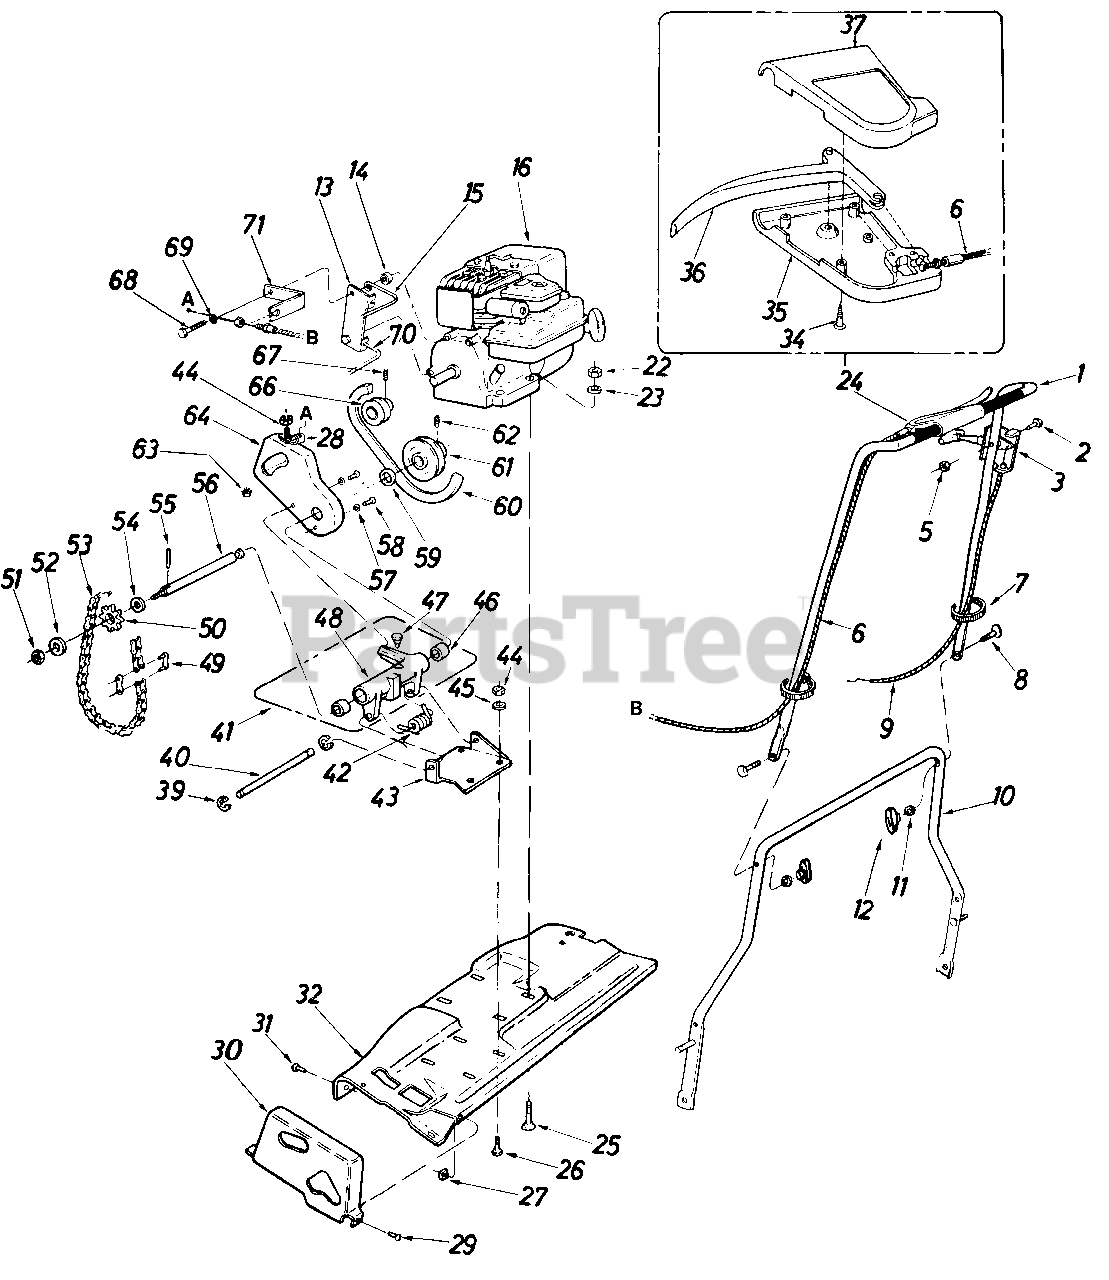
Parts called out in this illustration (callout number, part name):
1	Upper Handle Ass'y.
2	Rd. Hd. Scr. 1/4-20 x 1.88" Lg.
3	Throttle Control Ass'y.
5	Capped Wash. Z-Nut
6	Clutch Control Cable
7	Cable Tie
8	Speclal Scr. 5/16-18 x 1.75" Lg.
9	Throttle Cable
10	Lower Handle Ass'y.
11	L-Wash. 5/16
12	Handle Knob
13	Belt Keeper Brkt.
14	Spacer
15	Belt Keeper-Upper
16	Engine
22	Hex Nut 5/6-18 Thd.
23	L-Wash. 5/16
24	Clutch Control Ass'y.
25	Carriage Bolt 5/16-18 x 1.375" Lg.
26	Scr. 1/4-20 x .625" Lg.
27	Hex L-Nut 10-32 Thd.
28	Clevis Lanyard Fitting
29	Ph. Hd. Scr. 10-32 x .375" Lg.
30	Chain Guard
31	Hex Sems Scr. 5/16-24 x .50 Lg.
34	Slotted Oval Self-Tap Scr. #10 x .87" Lg.
35	Rear Control Cover
36	Lever Clutch Control
37	Front Cover Control
39	Retaining Ring
41	Jack Shaft Hsg. and Brg. Ass'y.
42	Spring
43	Bracket
44	Hex Nut 1/4 -20 Thd.
45	1/4 Split L-Wash.
46	Bearing
47	Oiler
48	Jack Shaft Hsg.
49	Connector Link
50	Sprocket
51	Hex Jam Nut 5/16-24
52	Washer
53	Chain
54	Wash. 5/8 x 15/16
56	Jack Shaft
57	Washer
58	Ph. Hd. Scr. 10-32 x .50" Lg.
59	Wash. 5/8 x 15/16
60	"V" Belt
61	Pulley Ass'y.
62	Roll Pin
63	Hex Nut 1/4-20 Thd.
64	Belt Guard Ass'y.
66	Pulley
67	Set Scr. 5/16-24 x 7132" Lg.
68	Ph. Hd. Scr. 1/4-20 x 1.75" Lg .
69	L-Wash. 1/4" Scr.
70	Belt Keeper-Lower
71	Clutch Cable Bracket
